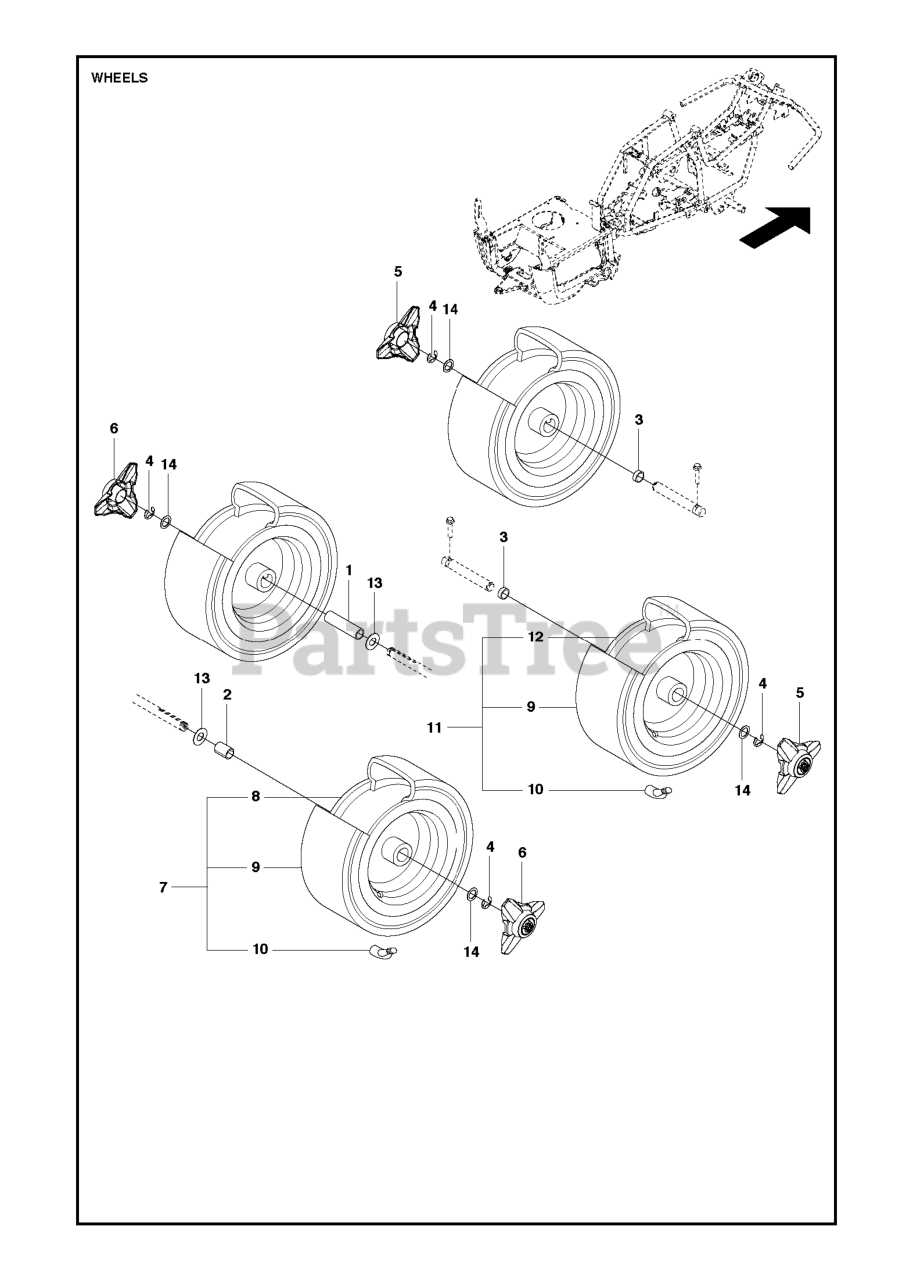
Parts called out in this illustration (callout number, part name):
4	RETAINING RING
9	TIRE
10	VALVE
